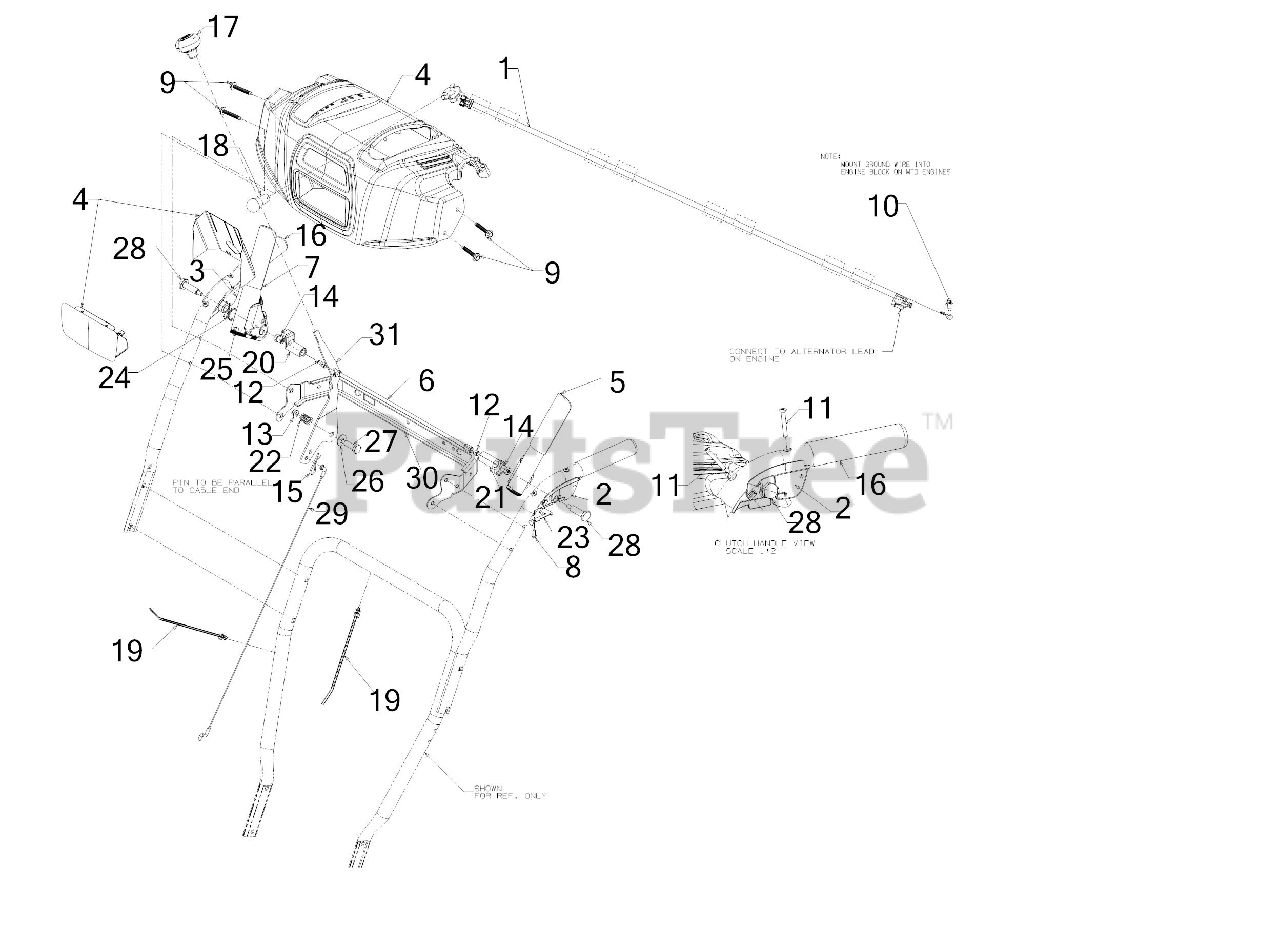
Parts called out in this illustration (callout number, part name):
1	LIGHT HARNESS ASSEMBLY
2	CLUTCH LOCK HANDLE ASSEMBLY (LH)
3	CLUTCH LOCK HANDLE ASSEMBLY (RH)
4	HANDLE PANEL ASSEMBLY (CRAFTSMAN)
5	HANDLE ASSEMBLY (LH)
7	HANDLE ASSEMBLY (RH)
8	SCREW #8-16 x .50
9	SCREW 1/4-20 x 1.625
10	SCREW 1/4-20 X.500
11	SCREW #10-24 x 1.375
12	SCREW 1/4-20 x .50
13	FLANGE LOCK NUT
14	HEX NUT W/PATCH
15	INTERNAL COTTER PIN
17	SHIFT KNOB
19	PUSH MOUNT TIE
21	CLUTCH LOCK CAM
22	COMPRESSION SPRING
23	CLUTCH SPRING
24	TORSION SPRING
25	RUBBER BUMPER
26	FLAT WASHER
27	SHOULDER SCREW
28	SHOULDER SCREW .437 x 1.345 1/4-20
29	SPEED SELECTOR CABLE (PLASTIC)
30	HANDLE SUPPORT BRACKET
